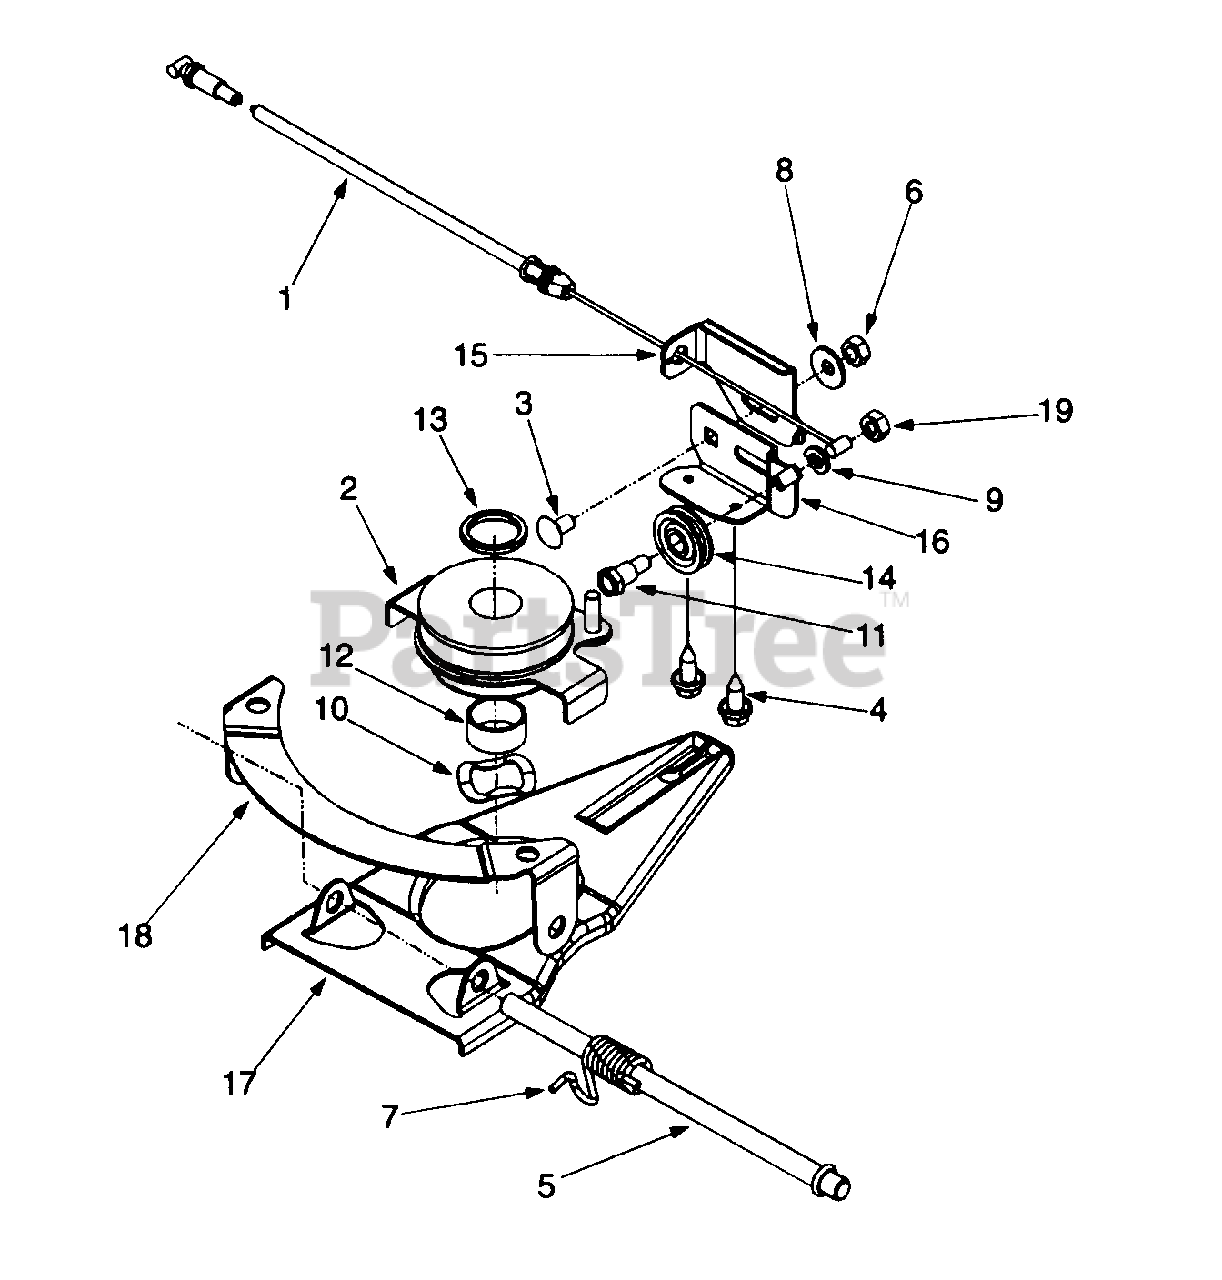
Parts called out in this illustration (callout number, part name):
1	6 Speed Cable
2	Pulley Ass'y Multi-Speed
3	Carriage Screw 1/4-20 x .50
4	Hex Washer Screw 1/4-14 x .625
5	Pivot Shaft
6	Nut 1/4-20
7	Torsion Spring LH
8	Bell Washer .265 x .75 x .062
9	Lock Washer 1/4 Reg Duty
10	Wave Washer 1.38 x .88 x .029
11	Shoulder Screw .375 x 1/4-14
12	Sleeve Spacer .88 ID x 1.00 OD
13	Sleeve Spacer .88 ID x 1.13 ID
14	Roller Cable
19	Hex Nut 1/4-28
